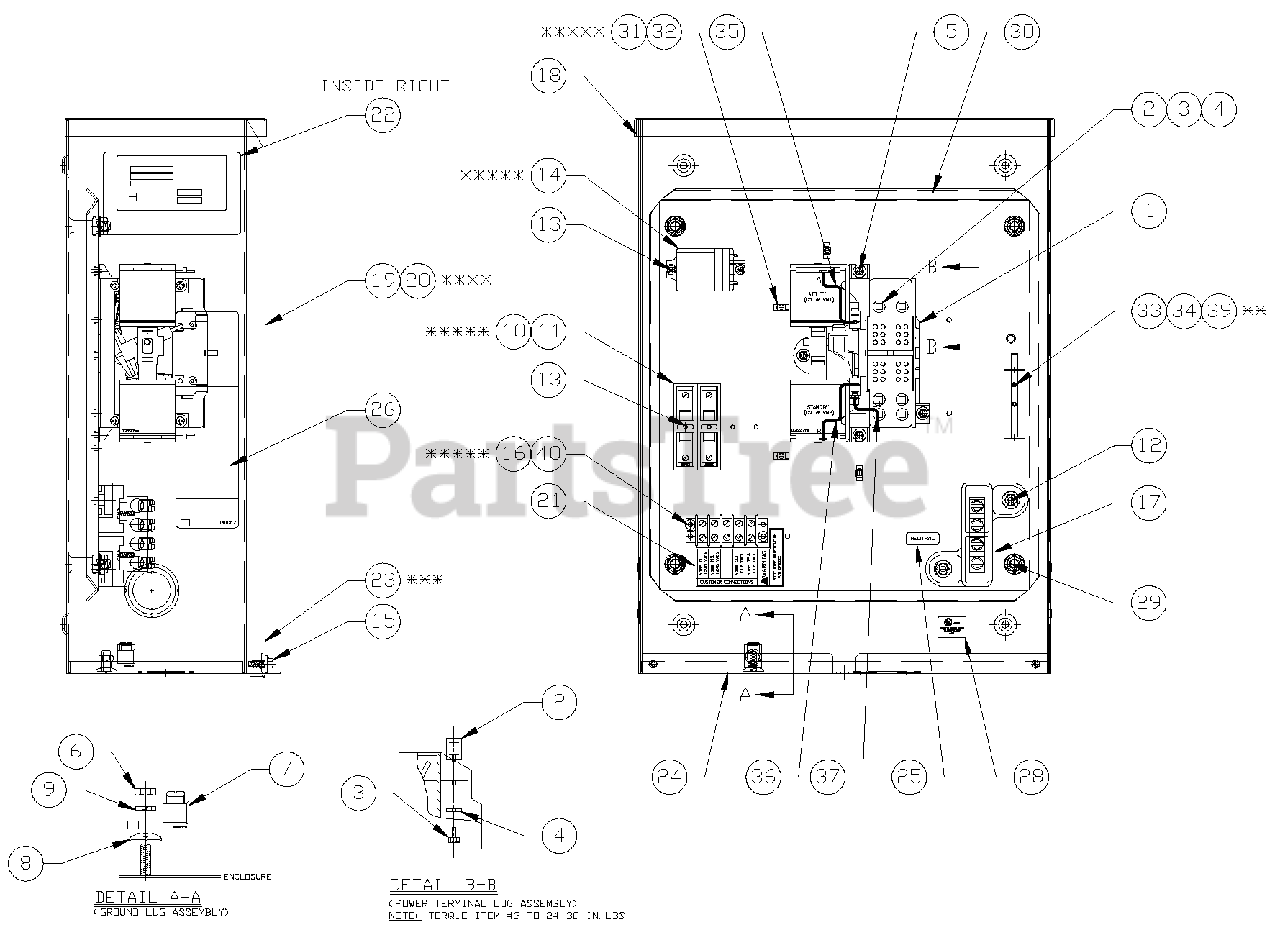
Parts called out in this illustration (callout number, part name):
1	TR SW-HSB 100A 2P 250V
2	LUG SLDLSS 1/0-#14 X 9/16 AL/CU
3	SCREW PPHM #10-32 X 1/4
4	WASHER LOCK #10
5	SCREW HHTT M5-0.8 X 10 BP
6	NUT HEX M8-1.25 G8 YEL CHR
7	LUG SLDLSS 2/0-#12 X 11/32 CU
8	WASHER LOCK SPECIAL 5/16
9	WASHER LOCK M8-5/16
10	FUSE 5A X BUSS
11	FUSE HOLDER
12	SCREW HHTT M6-1.0 X 12 ZINC
13	SCREW HHTT M4-0.7 X 10 BP
14	RELAY PNL 12VDC DPDT 10A@240VA
15	SCREW TH-FRM M6-1 X 16 N WA Z/JS
16	RIVET POP .156 X .675 AL
17	ASSY NEUTRAL BLOCK 100A
18	WELDMENT XFER SW BOX HSB
19	COVER TRANSFER SWITCH BOX HSB
21	DECAL TERMINAL STRIP
22	DECAL SWITCH RATING
23	DECAL-LIVE CIRCUIT
24	DECAL GROUND LUG
25	DECAL NEUTRAL
26	DECAL MANUAL 5A FUSE
28	DECAL-UL LIST HSB
29	NUT HEX FL WHIZ 3/8-16
30	SUBPLT TRANSFER SWITCH HSB
31	HOLDER CABLE TIE
32	TIE WRAP UL 3.9" X .10" NATL
33	BRACKET, ARM EXTENDER
34	ARM EXTENDER PIN
37	WIRE E1
39	SCREW HWHS #6-25 X 3/8 ZNC
40	BLOCK TERM 20A 5 X 6 X 1100V
